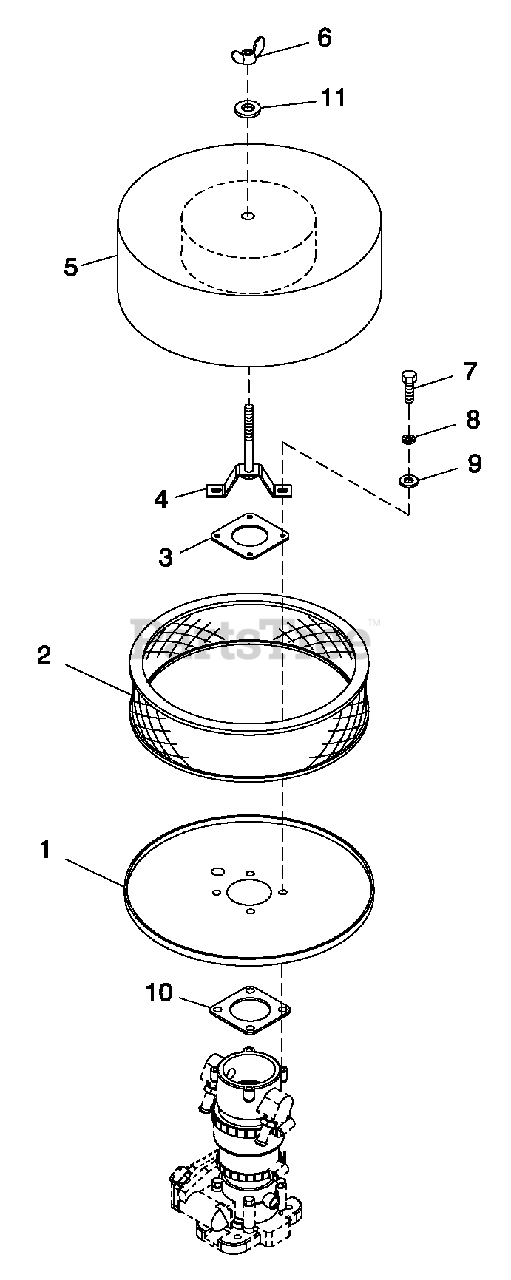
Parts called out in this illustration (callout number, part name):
1	AIR CLNR BTM PLT W/CPLR 8.1L
2	ELEMENT AIR FILTER
3	TOP PLATE VENTURI
4	HOLD DOWN AIR CLEANER PLATED
5	PLATE AIR CLEAN TOP 5.4L/6.8L
6	NUT WING 1/4-20 NYLK
7	SCREW HHC M6-1.0 X 16 G8.8
8	WASHER LOCK M6-1/4
9	WASHER FLAT M6
10	GASKET MIXER BOD Y
11	WASHER FLAT 1/4-M6 ZINC
